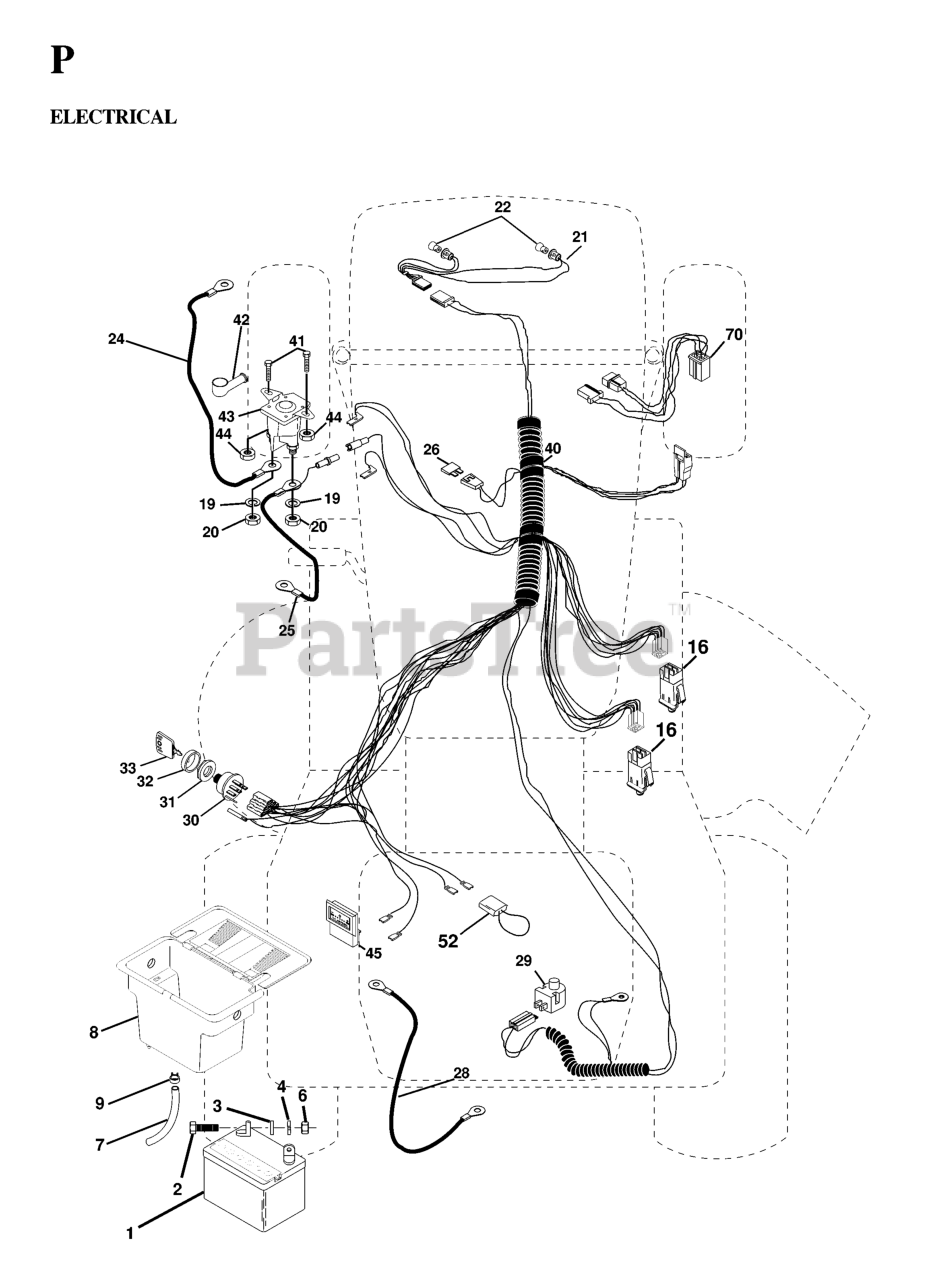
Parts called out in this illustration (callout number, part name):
1	BATTERY.DRY.30.AMP
2	BOLT.HEX.1/4.X.3/4.DICHROMATE
4	LOCKWASHER
6	NUT
7	TUBE BATTERY DRAIN
8	CASE BATTERY MECH HINGE
9	HOSE CLAMP T
16	SWITCH INTERLOCK
19	LOCKWASHER
20	NUT
21	HARNESS LIGHT SOCKET
24	BATTERY CABLE GT
25	CABLE BATTERY
28	CABLE T
29	RP.SWITCH.PLUNGER.NC.GRAY
30	SWITCH.IGNITION.4.POSITION
31	NUT IGNITION
32	COVER SWITCH KEY
33	KEY.MOLDED.GENERIC
40	HARNESS IGN
41	BOLT
42	TERMINAL COVER
43	SOLINOID
44	Nut, Keps Blk Hex 1/4-20 UNC
45	AMMETER
52	WIRE PROTECTION LOOP
70	HARNESS ENGINE
